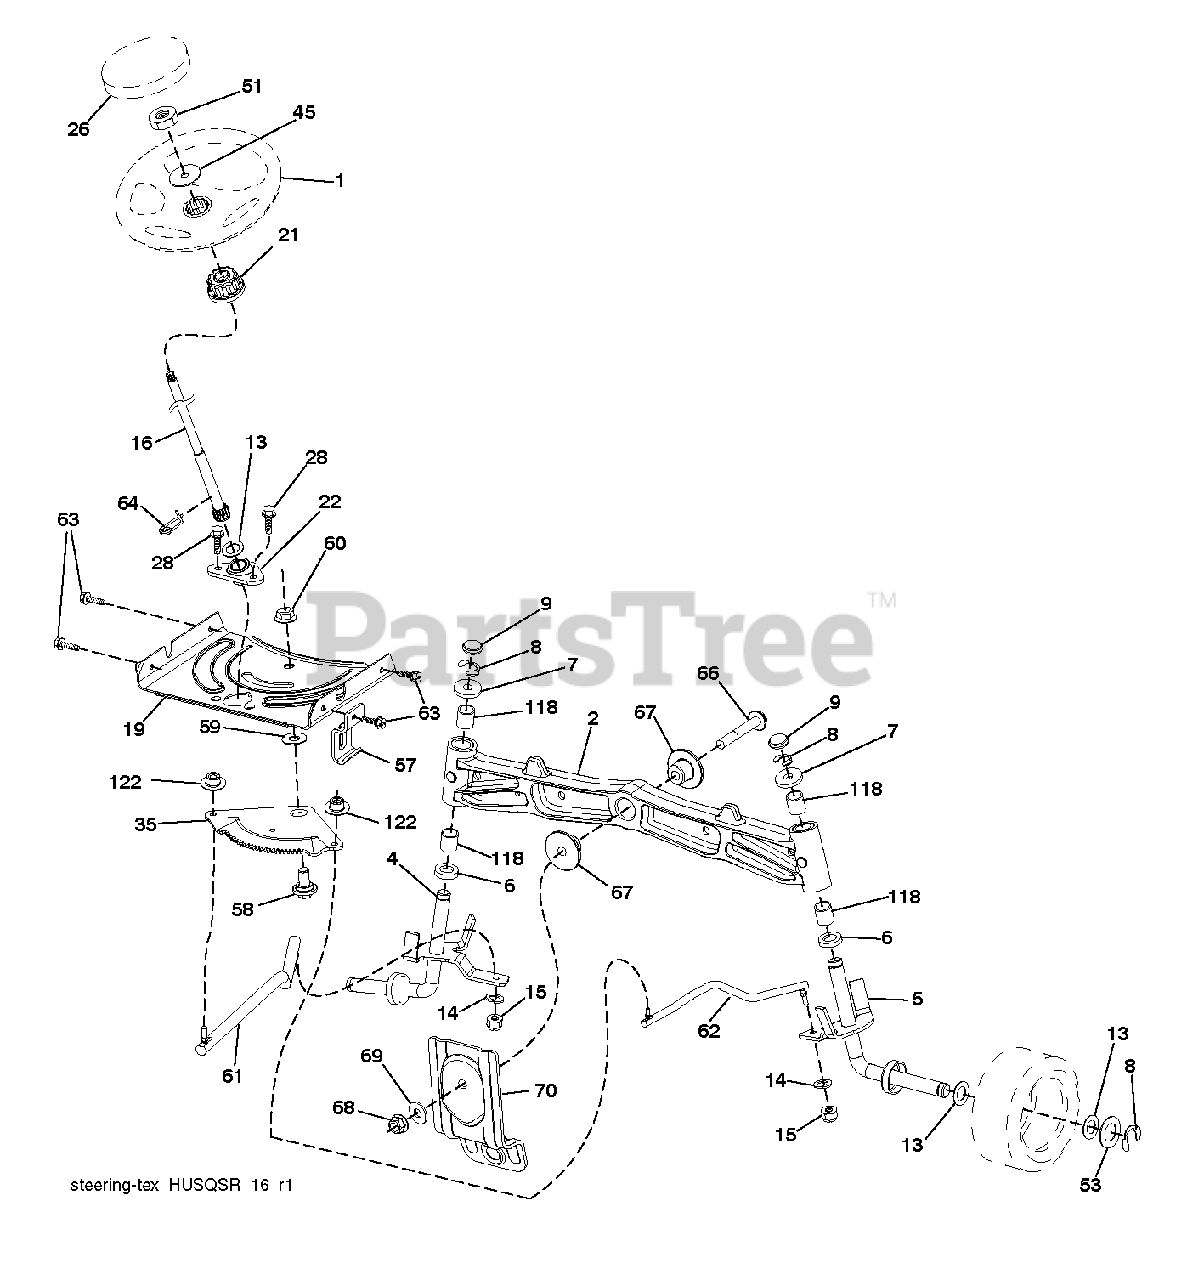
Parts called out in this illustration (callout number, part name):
1	WHEEL.STEER.HUSQ.SR.498.OVMLD
2	AXLE.SVC.ASM CAST IRON.TEX
4	SPINDLE.WELDED.LH.16"TEX
5	SPINDLE.WELDED.RH.16"TEX
6	THRUST WASHER
9	CAP.SPINDLE.BLACK
14	WASHER, LOCK 3/8
15	NUT CROWNLOCK 3/8-24
16	SHAFT.STEER.STEALTH.DD
19	PLATE.STEER.DDL.NLT/NG
21	ADAPTER, WHEEL STNG..
22	STEERING.SUPT.LOWER.
26	INSERT.CAP.WHL.STRG.HUSQ.PREM
28	SCREW, 3/8-16X3/4
35	GEAR.SECTOR.PLATE.DDL.
45	WASHER 9/16"ID, 2 3/8"OD
51	NUT.HEX.1/2-20
53	WASHER.HARDENED
57	BRKT.UPSTOP.GT/LT.TEX
58	BOLT.SHOULDER.SECTOR.P
59	WASHER.THURST.SECTOR.S
60	NUT FLANGE LOCK 5/8-11
61	DRAGLINK.LH.BALLSTUD.D
62	DRAGLINK.RH.BALLSTUD.D
63	SCREW
64	RETAINER.CLIP.SPRING.S
66	BOLT HEX FGHD 7/16-14 X 3 SERR
67	BUSHING.PM.FRONT AXLE
68	NUT.LOCK.FLANGE.7/16
69	WASHER.1.5X.505X.118
70	BRKT.DECK.SUSPENSION.F
118	BUSHING, AXLE CAST
122	CAP.GEAR.SECTOR.TEX
